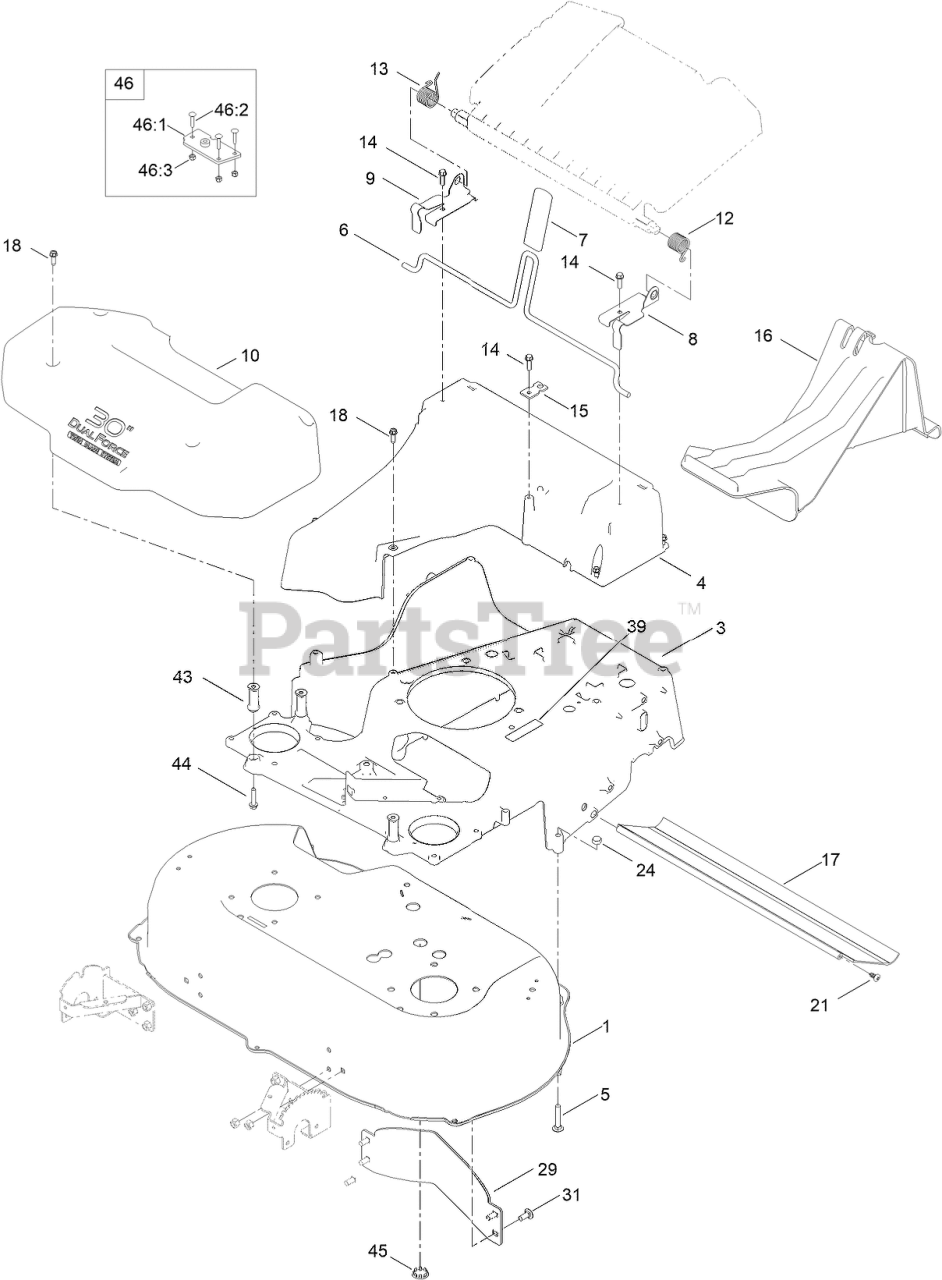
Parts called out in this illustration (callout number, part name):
1	HOUSING ASM
3	FRAME-30IN, 60V
5	BOLT-CAR
6	ROD-RELEASE, HANDLE
7	GRIP-LEVER
8	BRACKET-DOOR, LH
9	BRACKET-DOOR, RH
10	COVER-BELT
12	SPRING-TORSION
13	SPRING-TORSION
14	SCREW-HWH
15	BRACKET-CABLE, TRACTION
16	PLUG-MULCH
17	SHIELD-TRAILING
18	SCREW-HWHTF
21	SCREW-PTH
24	NUT-LOCK, NI
29	BAFFLE-CONTROL
31	SCREW-HWHTF
39	DECAL-PROP 65, SHORT, TRILINGUAL
43	SPACER-FRAME, 30 IN.
44	SCREW-HWHTF
45	PLUG-BUTTON
46	FRAME-PLATE KIT
46:1	PLATE-FRAME, ASM
46:2	SCREW-CARR
46:3	NUT-LOCK, NI
